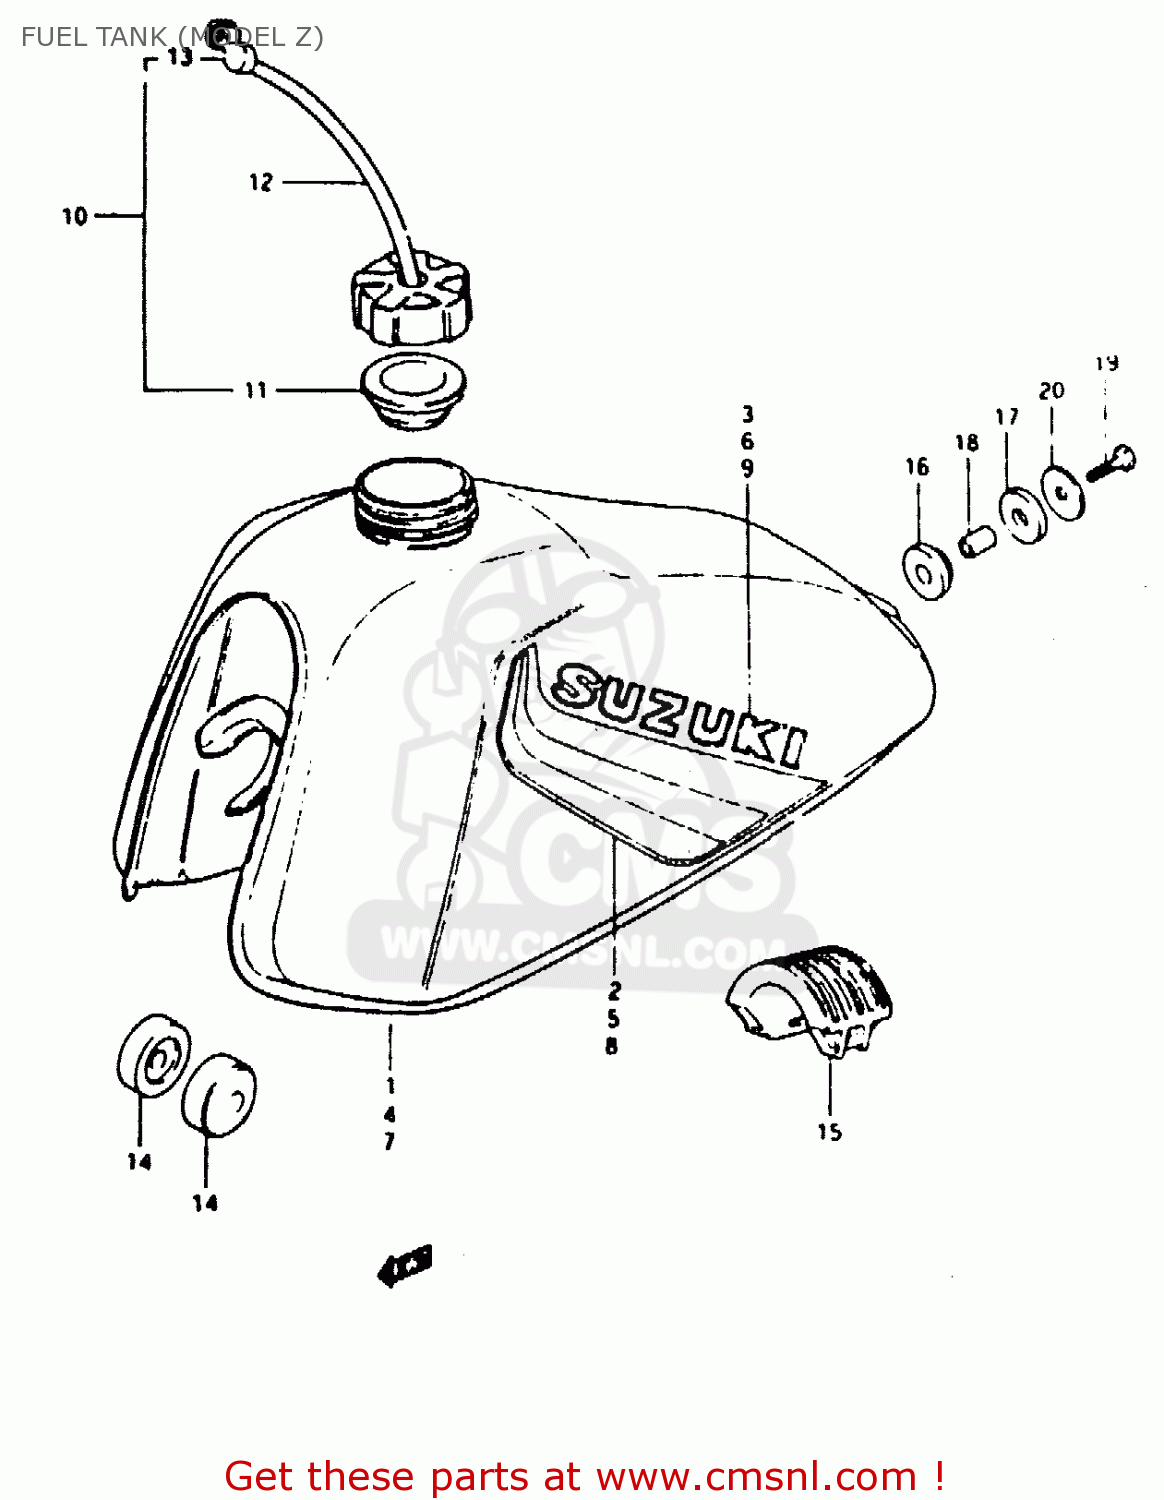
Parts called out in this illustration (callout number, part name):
1	TANK, FUEL (RED)
2	TAPE SET
3	EMBLEM
4	TANK, FUEL (BLUE)
5	TAPE SET
6	EMBLEM
7	TANK, FUEL (YELLOW)
8	TAPE SET
9	EMBLEM(BLACK)
10	CAP SET,FUEL TANK
11	GASKET,FUEL TANK CAP (NAS)
12	HOSE
13	CLAMP,FUEL TANK BREATHER HOSE
14	CUSHION
15	CUSHION,FUEL TANK UPR
16	CUSHION
17	CUSHION
18	SPACER(8.5X12X19)
19	BOLT (8X30)
20	WASHER (8.5X29X1.6)
